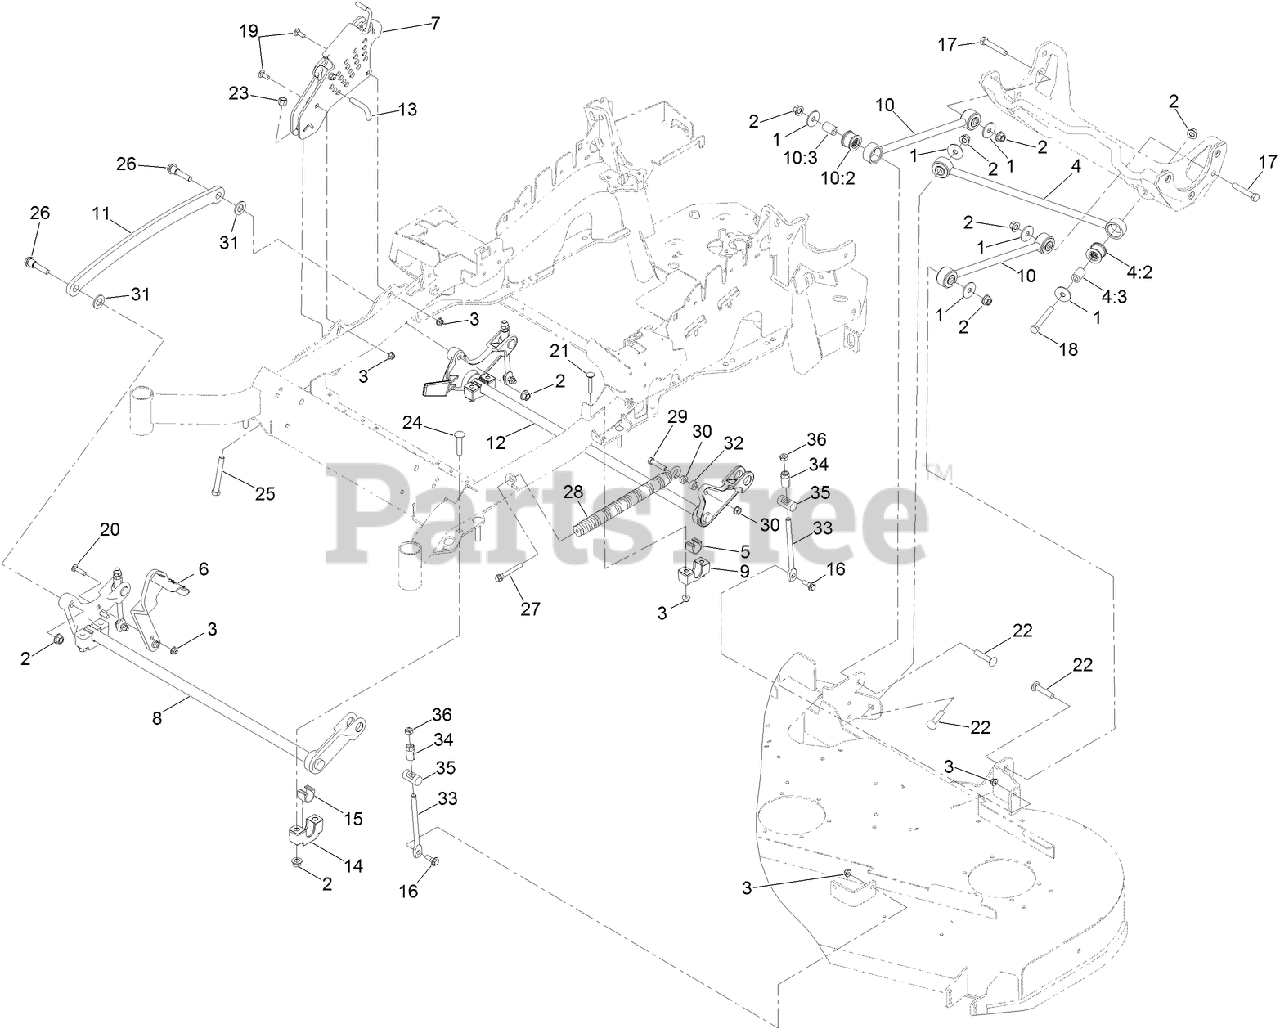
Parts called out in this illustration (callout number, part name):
1	WASHER-THRUST
2	NUT-LOCK
3	NUT-HF, NI
4	PANHARD ROD ASM
4:2	BUSHING-SUSPENSION, RUBBER
4:3	SPACER
5	BEARING-CROSS SHAFT, REAR
6	LEVER-FOOT
7	HEIGHT-OF-CUT ASM
8	DECKLIFT-FRONT
9	SUPPORT-CROSS SHAFT, BEARING REAR
10	DECK STRUT ASM
10:2	BUSHING-SUSPENSION, RUBBER
10:3	SPACER
11	LINK-LIFT, DECK
12	LIFT-DECK, REAR
13	PIN-HOC
14	SUPPORT-CROSS SHAFT, BEARING
15	BEARING-CROSS SHAFT, FRONT
16	SCREW-SHOULDER, HHF
17	SCREW-HH
18	SCREW-HH
19	SCREW-HH
20	SCREW-HH
21	SCREW-HH
22	SCREW-CARR
23	NUT-LOCK, NI
24	BOLT-CARR
25	BOLT-TAP
26	SCREW-HHF, SHOULDER
27	BOLT-SHOULDER
28	SPRING-EXTENSION
29	SCREW-HH
30	NUT-HF
31	WASHER-FLAT
32	SPACER
33	LINK-ADJUSTER, DECK LIFT
34	ADJUSTER-LIFT, DECK
35	TRUNNION
36	NUT-JAM
